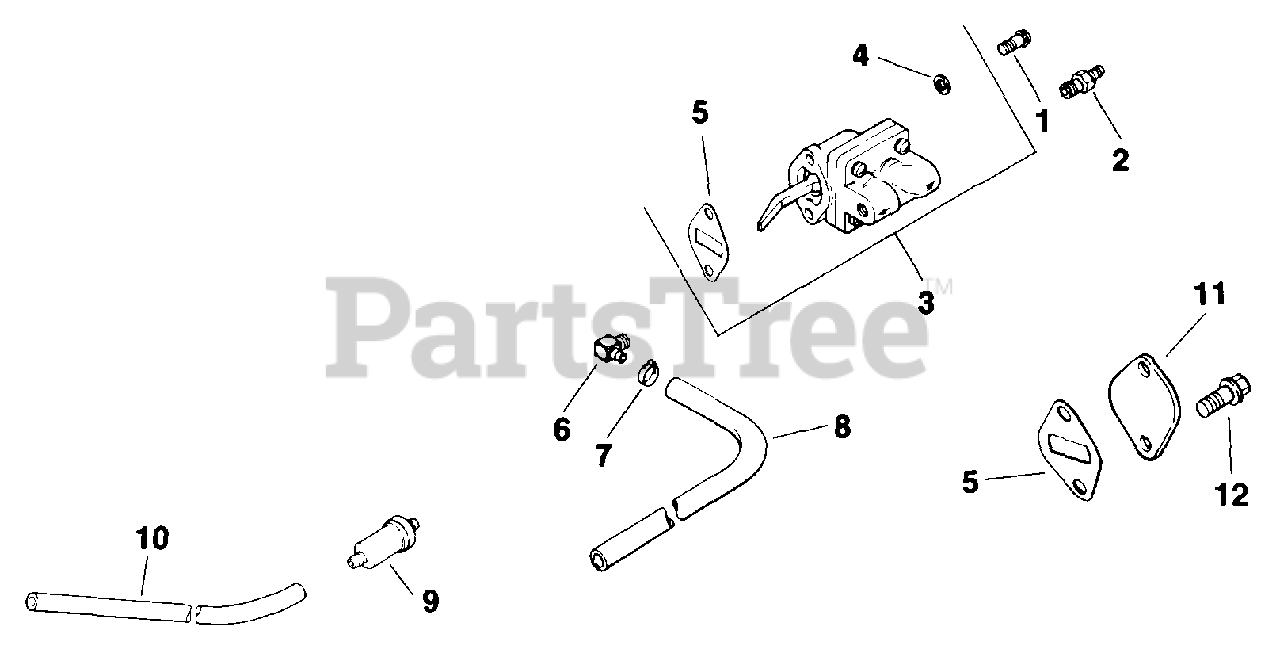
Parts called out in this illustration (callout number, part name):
1	SCREW, POZ TRS HD 1/4-20X5/8" - DISCONTINUED
2	CONNECTOR USE 25 326 03-S
4	WASHER, FLAT 1/4" (O.D. 1/2")
5	GASKET - USE 25 041 09
6	CONNECTOR, 90 DEG. HOSE
7	CLAMP, HOSE 1/2" USE 25 237 14-S
8	LINE
9	FUEL FILTER - USE 25 050 02
10	LINE, FLEXIBLE FUEL
